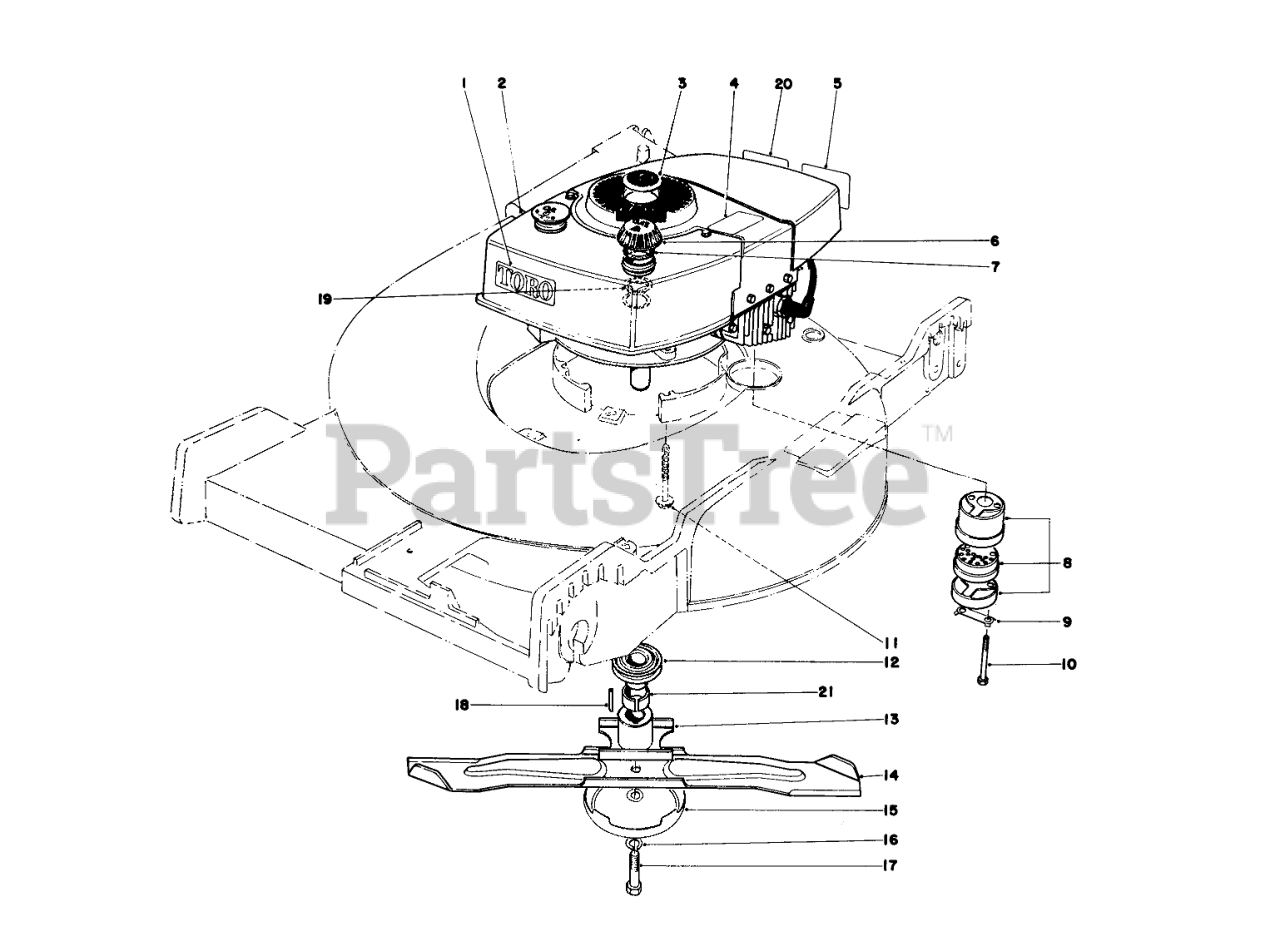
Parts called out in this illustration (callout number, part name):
1	Decal Toro
2	Engine
3	Plug Button
4	Decal Lockout
5	Decal Maintenance
6	Gas Cap Assembly (Incl. Ref. #7 & 19)
7	GASKET
8	Muffler Assembly (Incl. Ref. #9 & 10)
9	CLIP - LOCKING
10	SCREW-HH
11	3/8-16 X 2-3/4 CAPSCR
12	PULLEY DRIVER
13	BLADE RETAINER WA
14	Blade
15	AntiScalp Cup
16	WASHER-LOCK
17	BLADE SCREW
18	KEY-SQUARE
19	GAS CAP BAFFLE
20	Decal-Maintenance
21	Pulley Spacer
